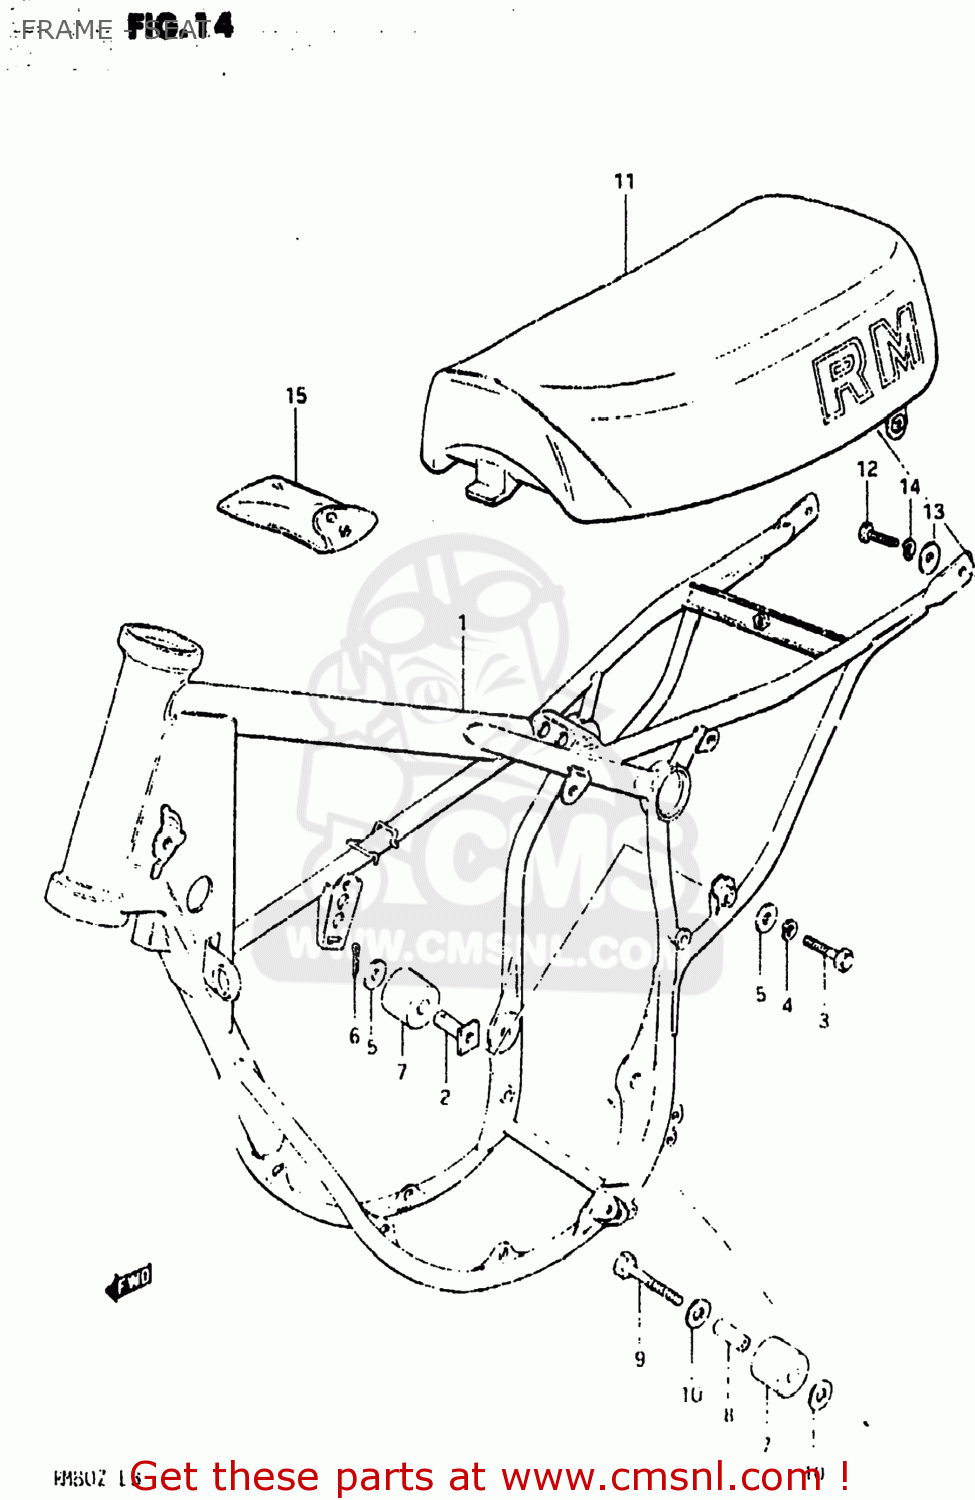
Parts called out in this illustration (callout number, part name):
1	FRAME
2	BOSS,CHAIN CONTROL
3	BOLT
4	LOCK WASHER
5	WASHER
6	PIN 25X20
7	ROLLER,CHAIN LENGTH CONTROLLER
8	SPACER (6.5X10.5X29)
9	BOLT 6X40
10	WASHER
11	SEAT ASSEMBLY
12	BOLT
13	WASHER
14	LOCK WASHER
15	TOOL SET
